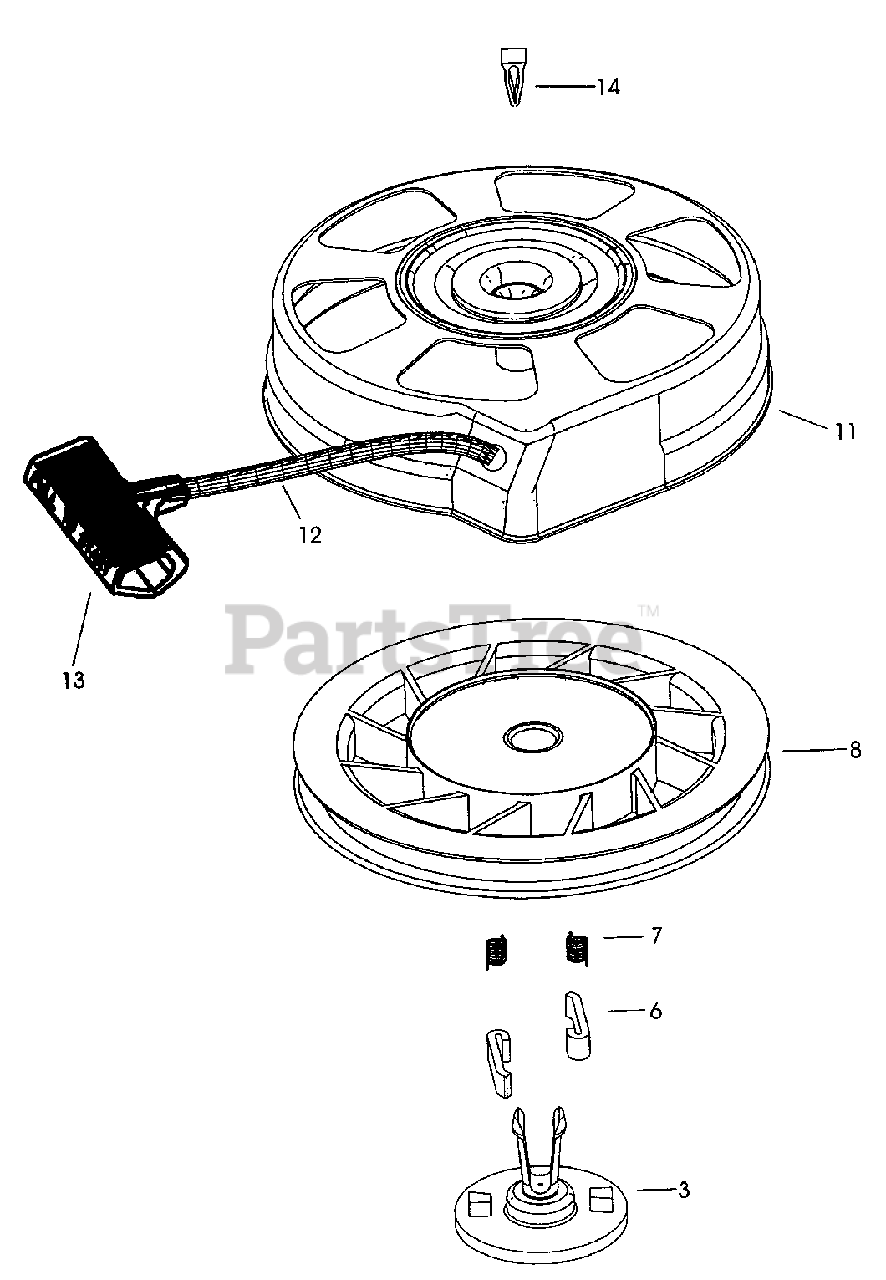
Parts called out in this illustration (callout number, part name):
3	Retainer
6	Starter Dog
7	Dog Spring
8	Pulley & Rewind Spring Ass'y
11	Starter Housing Ass'y (40 degree grommet)
12	Starter Rope (Length 98" x 9/64" dia.)
13	Starter Handle
14	Locking Tab
